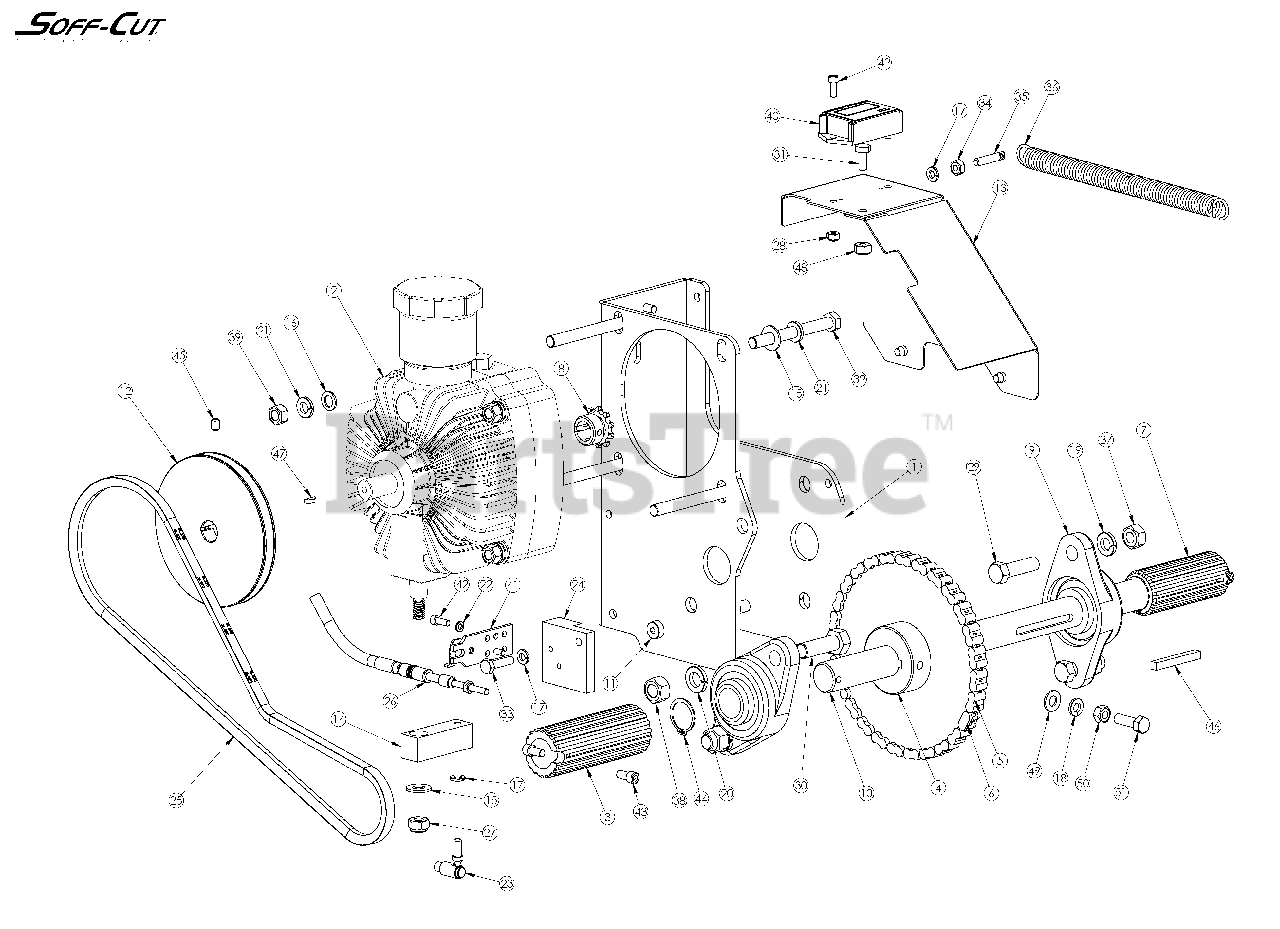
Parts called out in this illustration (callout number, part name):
2	HYDROSTATIC PEDAL ASSY
15	FLAT WASH 3/8 STL CAD
32	HEX BOLT 3/8-16-3 1/2 CAD GR 5
45	SET SCREW 1/4-20-3/8 KNURLED P
48	NYLOC NUT 1/4-20 CAD PL.
51	HEX BOLT 5/16-18-1 CAD GR 5
